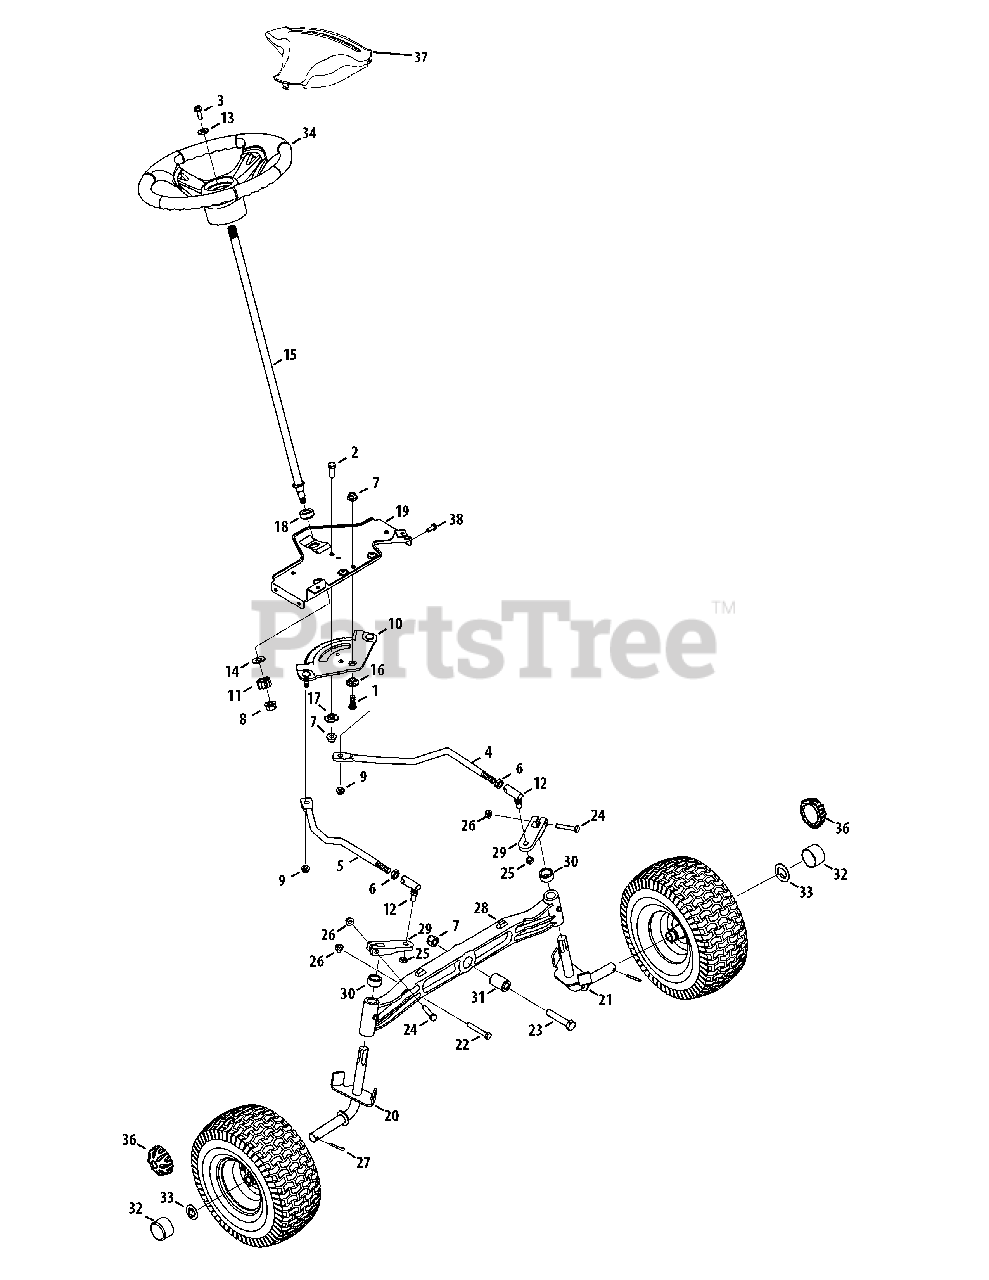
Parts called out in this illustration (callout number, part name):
1	Screw, 3/8-16 x 1.0
2	Hex Screw 3/16 x 1.00
3	Hex Screw 5/16-18 x 1.00 Spe cial
4	Link, Drag LH
5	Link, Drag RH
6	Hex Jam Nut 7/16-20
7	Flange Lock-Nut 3/8-16 Gr. F Nylon
8	Flange Lock Nut, 7/16-20
9	Hex Flange L-Nut 5/16-18
10	Steering Gear, 11/90 Ra tio
11	Steering Pinion Gear
12	Ball Joint, 7/16 - 20
13	Flat Washer .406 ID x .875 DE x .105
14	Fl. Washer .510 x 1.120 x .060
15	Steering Shaft .625 OD x 24.25
16	Shoulder Spacer .385 x 1.25 x .3025
17	Shoulder Spacer .385 x 1.25 x .3025
18	Hex Flange Bear ing 5/8
20	Axle Ass’y RH .750 Dia. (46" Deck)
20	Axle Ass’y RH .750 Dia. (50" Deck)
21	Axle Ass’y LH .750 Dia. (42" Deck)
21	Axle Ass’y LH .750 Dia. (46" Deck)
21	Axle Ass’y LH .750 Dia. (50" Deck)
22	Hex Bolt 5/16-18 x 2.25
23	Hex Cap Screw, 3/8-16 x 2.5
24	Hex Screw 5/16-18 x 1.75" Lg.
25	Hex Cent L-Nut 3/8-24
26	Flange Locknut 5/16-18 Gr. F, Nylon
27	Cotter Pin 5/32" Dia.
28	Pivot Bar (cast)
29	Steering Block
30	Spacer .710 ID x .125 OD x .56
31	Spacer .385 x 1.0 x 1.5075
32	Hub Cap
33	Flat Washer .350 x 1.559 x .062
34	Steering Wheel, Standard Grip
34	Steering Wheel, Softgrip
36	Hub Cap
37	Steering Wheel Cover (w/sprigs)
38	S-Tapp Screw. 5/16-18 x .75
